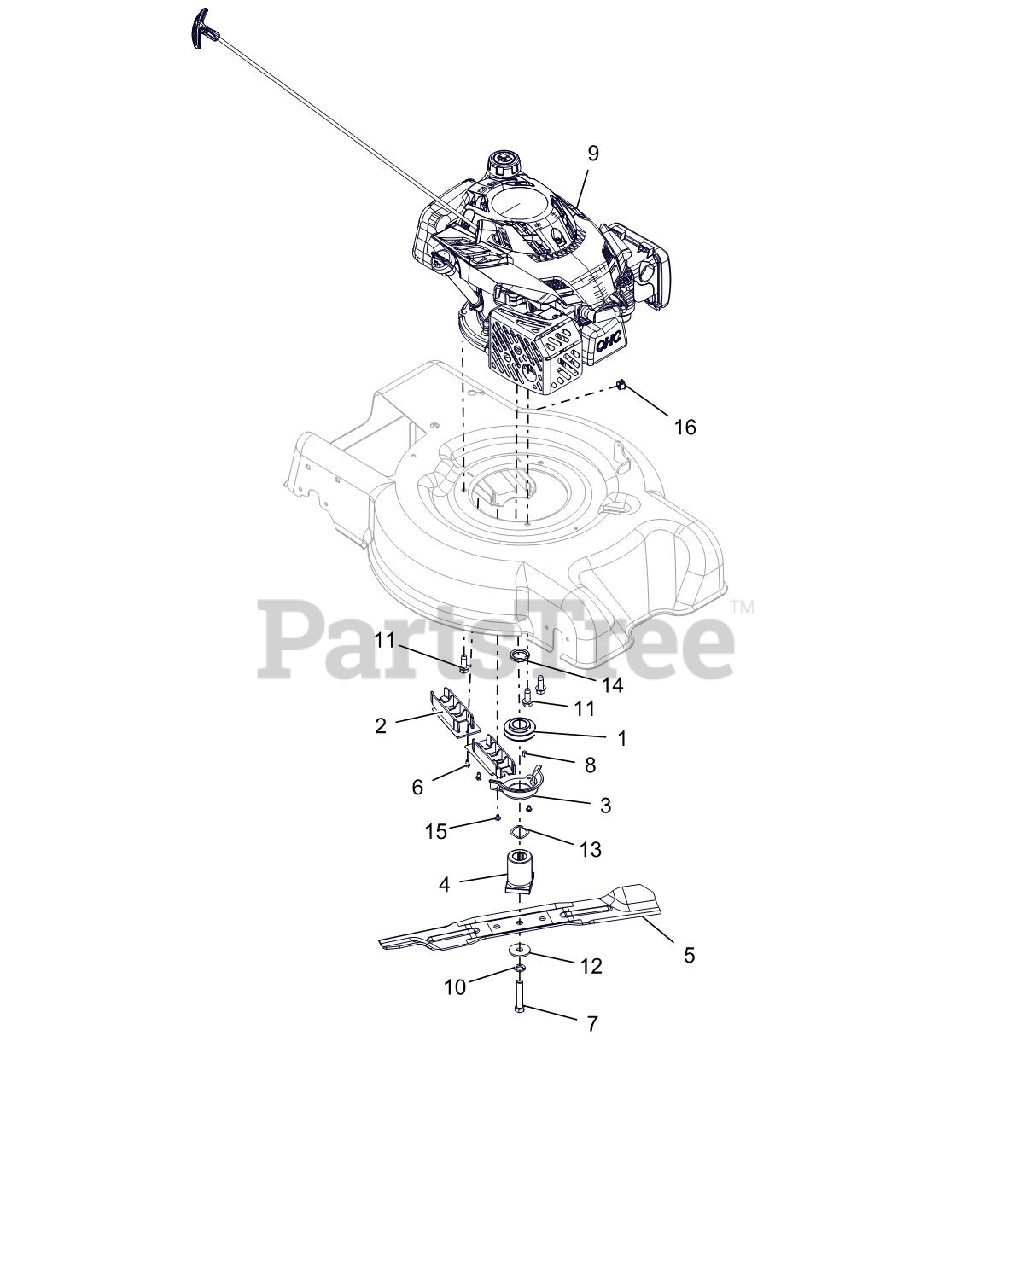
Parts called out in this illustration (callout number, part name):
1	PULLEY, GROUND DRIVE, LM
2	GUIDE, BELT INNER
3	GUIDE, BELT CRANK
4	ADAPTER, BLADE
5	BLADE, MOWER 21" HIGH LIFT
6	SCR-TAP 10-24X.375 PRE-COAT 80
7	@BLT-HEX .4375-20X2.25 GR8 YWZ
8	KEY-SQ .188X.188X.375
9	ENGINE, SUBARU 175CC VERT. ES
10	@WSHR-LK .44X.109 REG YWZC
11	@SCR-TAP .38-16X1.00 HWH TR YZ
12	WSHR-FL-STL .4375X1.50X.125 YZ
13	WASHER - WAVE 1.09X1.37X.016
14	SPCR, 1.00 X 1.375 X .179
15	SCR-TAP 10-24X.25 CRSLPH TR YZ
16	PLUG, DOME-BLACK, .625 DIA
